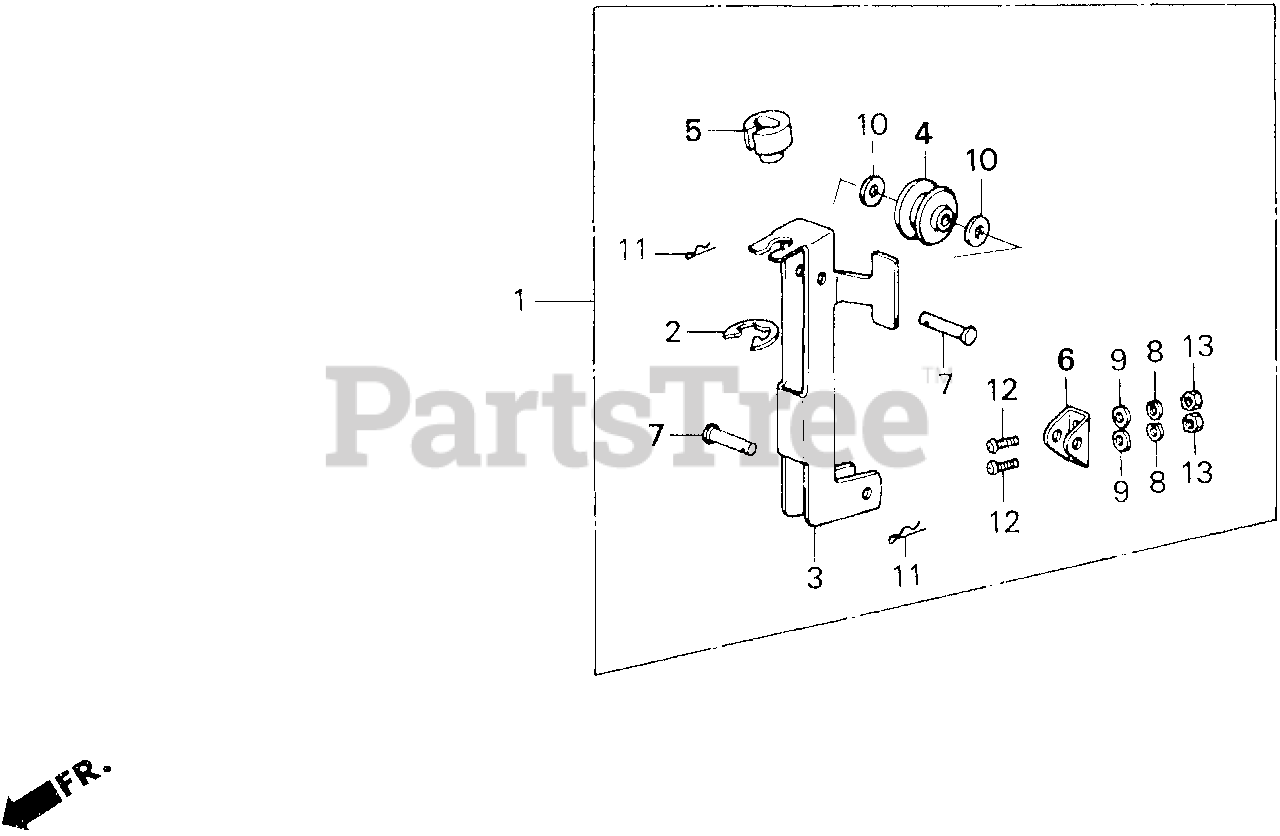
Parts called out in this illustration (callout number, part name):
1	STARTER KIT, VERTICAL (N/A: SEE COMPONENTS)
3	STAY, VERTICAL STARTER
4	IDLER, VERTICAL STARTER
5	GUIDE, ROPE
6	BRACKET, VERTICAL STARTER
7	PIN, VERTICAL STARTER
8	WASHER, SPRING (6MM)
9	WASHER, PLAIN (6MM)
10	WASHER (10MM)
11	PIN, LOCK (10MM)
12	SCREW, PAN (6X12)
13	NUT, HEX. (6MM)
